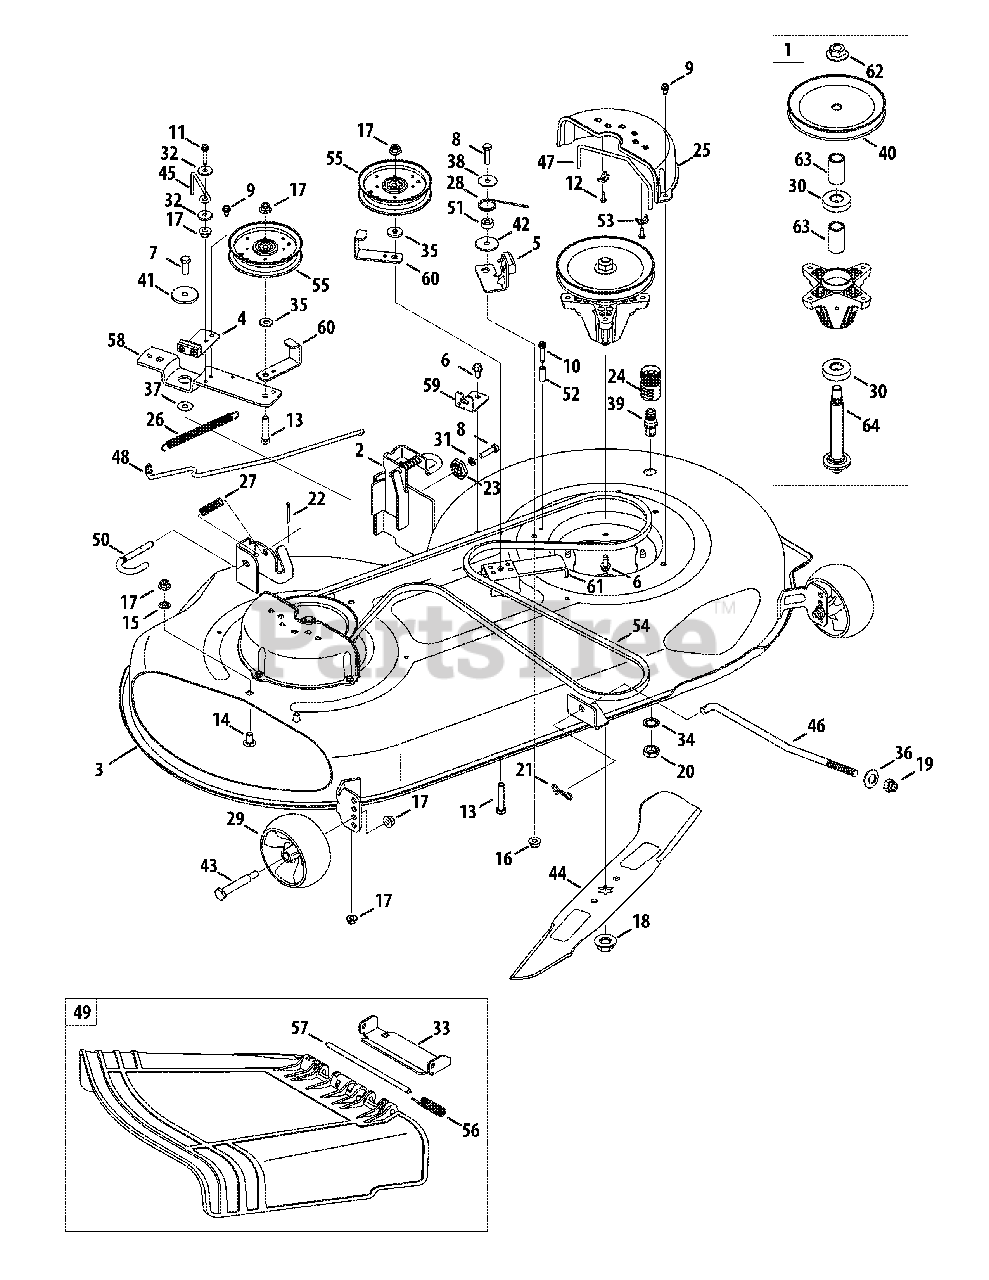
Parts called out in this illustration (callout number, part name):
1	Spindle Assembly, Pul 6.93 Dia
2	Bracket Assembly, Deck Hanger, LH
3	Deck Assembly, Offset, 46"
4	Brake Assembly, Deck, 42/46
5	Brake Assembly, Deck, 46"
6	Screw, Self-tapping, 5/16-18, .750,
7	Hex Screw, 3/8-16, 1.00, Gr5, Std
8	Hex Screw, 5/16-18, 1.25, Gr5, Std
9	Screw, Self-tapping, 1/4-20, 0.500
10	Screw, Self-tapping, 1/4-20, 1.500
11	Screw, Self-tapping, 1/4-20, 1.250
12	Screw, B, #10-16, 0.625
13	Hex Screw, 3/8-16, 2.00, Gr5, Std
14	Bolt, Carriage, 3/8-16, 0.75, Gr1
15	Nut, Push, 3/8
16	Nut, Flange Lock, 5/16-18, Nylon
17	Nut, Flange Lock, 3/8-16, Nylon
18	Nut, Flange, 5/8-18
19	Nut, Lock, 1/2-13
20	Nut, Hex, M16-1.5
21	Bow Tie Cotter Pin
22	Pin, Cotter, 1/8 x 1.25
23	Gear, Deck Adjustment
24	Adapter, Water Port
25	Belt Cover, Universal
26	Spring, Extension, .62 x 6.12
27	Spring, Compression, .535 x 1.751
28	Spring, Torsion, .992 ID x 1.17 OD
29	Wheel, Deck, 5.0 Dia Ball
30	Bearing, Ball, .787 x 1.85 x .551
31	Washer, Lock, 5/16, Regular Duty
32	Washer, Flat, .265 x .938 x .120
33	Bracket, Chute, 46
34	Washer, Lock, 5/8, Int Tooth
35	Washer, Flat, .385 x .870 x .092
36	Deck Pivot Cup
37	Washer, Flat, .385 x 1.0 x .030
38	Washer, Flat, .330 x 1.25 x .06, Ht
39	Deck Port, Water
40	Pulley, Deck, 6.93 Dia
41	Spacer, Shoulder, .8840 x .190
42	Spacer, Shoulder, .5000 x .1475
43	Bolt, Shoulder, .496 x 2.50, 3/8-16
44	Blade, Cut, 23.25" 2-In-1
45	Rod, Belt Keepr, 42 Idler
46	Rod, Lift, Deck
47	Rod, Keeper, Belt
48	Rod, Control, Brake 46"
49	Chute Assembly, 46" Offset
50	Rod, Deck Release
51	Spacer, .315 x .750 x .375
52	Spacer, .260 x .375 x 1.030
53	Clamp, Casing
54	Belt, V-Type, A-Sec
55	Pulley, Idler, 4.25"Dia
56	Spring, Torsion, .44 I.D. x 2.0
57	Pin, Hinge, 7.96
58	Bracket, Idler, Pivot, 46
59	Bracket, Cable, Deck Engagement
60	Bracket, Guard, Belt, 4.25 Pulley
61	Bracket, Support, Deck Idler
62	Nut, Flange, 5/8-18
63	Spacer, .792 x 1.060 x 1.860 Lg
64	Shaft, Spindle, 6.11 Lg.
